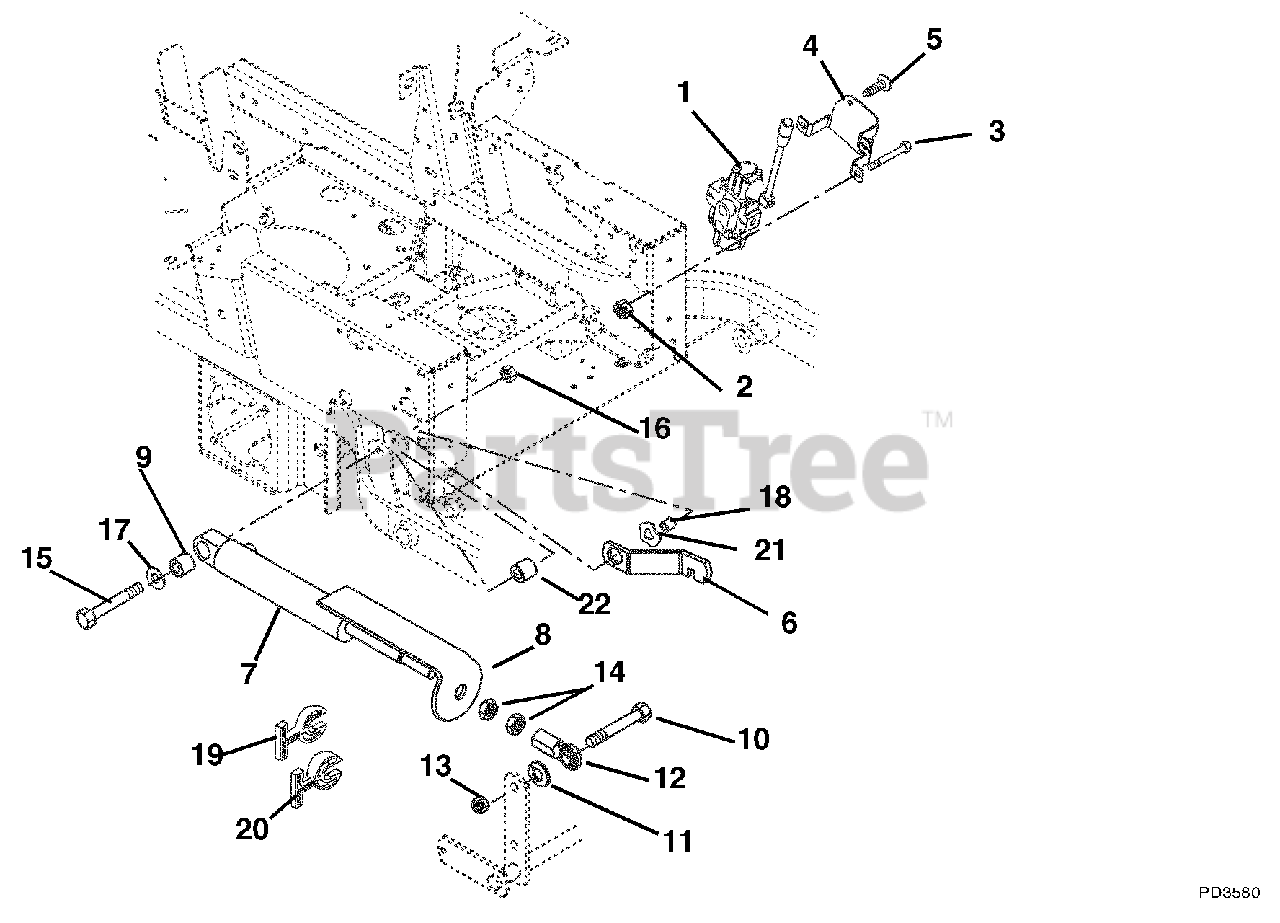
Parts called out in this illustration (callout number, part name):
1	Valve, Hydraulic
2	Nut-Locking-Top-Flange .31-18
3	Bolt-Hex .31-18 x 2.25 Grade 5
4	Valve Mounting Bracket
5	Screw-Tapping .38-16 x .50 Hex Washer Head
7	Cylinder-Hydraulic Lift
8	Strap, Cut Indicator/Guard
9	Bushing .516 x 1.000 x 1.050
10	Bolt-Hex .62-11 x 2.25 Grade 8
11	Washer-Lock .62 x .156
12	Rod End-Right Hand-Female 5/8
13	Nut-Locking-Center .62-11
14	Nut-Jam .625-18
15	Post, Cylinder Stop
16	Nut-Locking-Top-Flange .50-13
17	Washer-Flat-Steel .515 x 1.625 x .25
18	Bushing-Flange .515 x .75 x .275 x 1.12
19	Stop, Cylinder .34 Thick
20	Stop, Cylinder .68 Thick
21	Washer-Wave .076 x 1.12 xz .08
22	Spacer .50 I.D. x .88 O.D. x .88
